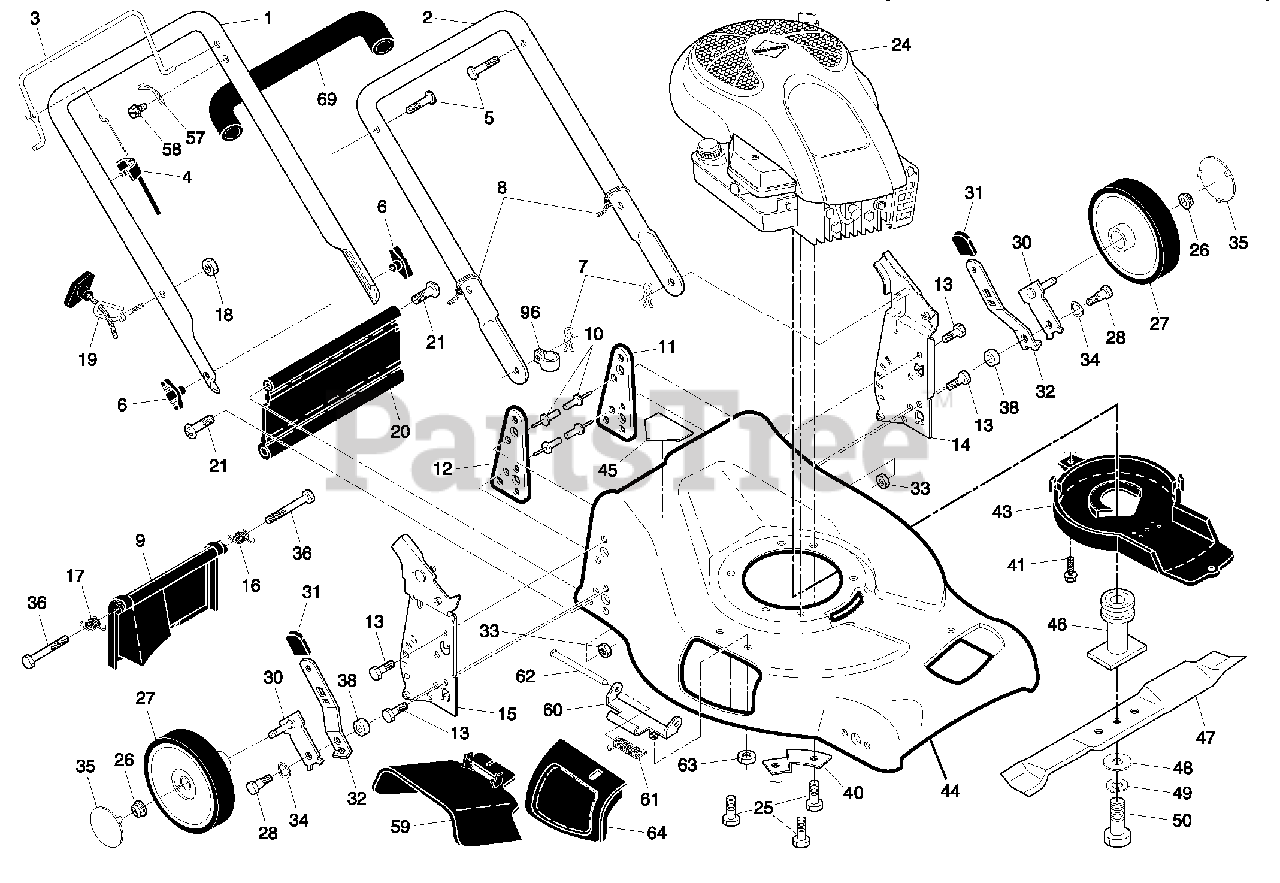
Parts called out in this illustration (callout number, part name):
1	Upper Handle Assembly
2	Lower Handle
3	Control Bar
4	Engine Zone Control Cable
5	Handle Bolt
6	Handle Knob
7	Hairpin Cotter
8	Wire Tie
9	Rear Door Assembly
10	Pop Rivet
11	Support Bracket, LH
12	Support Bracket, RH
13	Screw, Tapping 1/4-20 x 5/8
14	Handle Bracket, LH
15	Handle Bracket, RH
16	Spring, Rear Door, LH
17	Spring, Rear Door, RH
18	Nut, Hex 1/4-20
19	Rope Guide
20	Rear Skirt
21	Hinge Screw 1/4-20 x 1-1/4
25	Hex Head Thread Rolling Screw 3/8-16 x 1-1/8
26	Hex Flange Nut
27	Wheel & Tire Assembly
28	Shoulder Bolt 5/16-18 x 1-21/64
30	Axle Arm Assembly, Rear
31	Selector Knob
32	Selector Spring
33	Nut, Hex
34	Washer, Curved, Cylindrical
35	Hubcap
36	Bolt, Rear Door
39	Spacer
40	Mounting Bracket, Debris Shield
41	Screw, Debris Shield
43	Debris Shield
44	Kit, Lawn Mower Housing
45	Danger Decal
46	Blade Adapter / Pulley
47	Blade, 21"
48	Hardened Washer
49	Helical Washer
50	Screw, Hex Head, Grade 8, 3/8-24 x 1-3/8
57	Bracket, Upstop
58	Screw #10-24 x 1/2
59	Discharge Defl ector
60	Hinge Bracket
61	Hinge Spring
62	Hinge Rod
63	Nut, Hex
64	Mulcher Door
69	Foam Grip
96	Clip, Cable
96	Operator's Manual, English
96	Operator's Manual, French
96	Replacement Parts Manual
